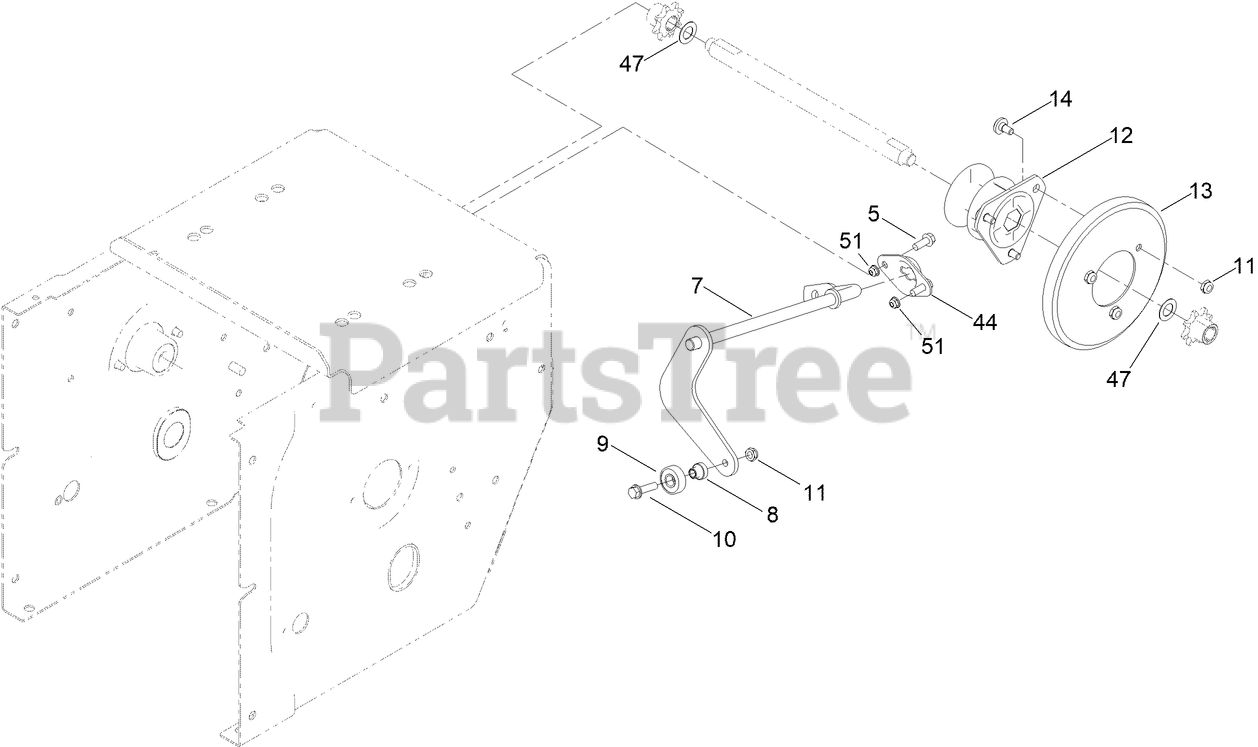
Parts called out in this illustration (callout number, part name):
5	SCREW-HHF
5	SCREW-HWH
7	ROD-SHIFT
8	SPACER-PLATE, SHIFT
9	BEARING-BALL
10	SCREW-HWHTF
11	NUT-HEX
12	TRUNNION
13	WHEEL-FRICTION
14	SCREW-SHOULDER
44	RETAINER-ROD, SHIFT
47	WASHER-PLAIN
51	NUT-HF
